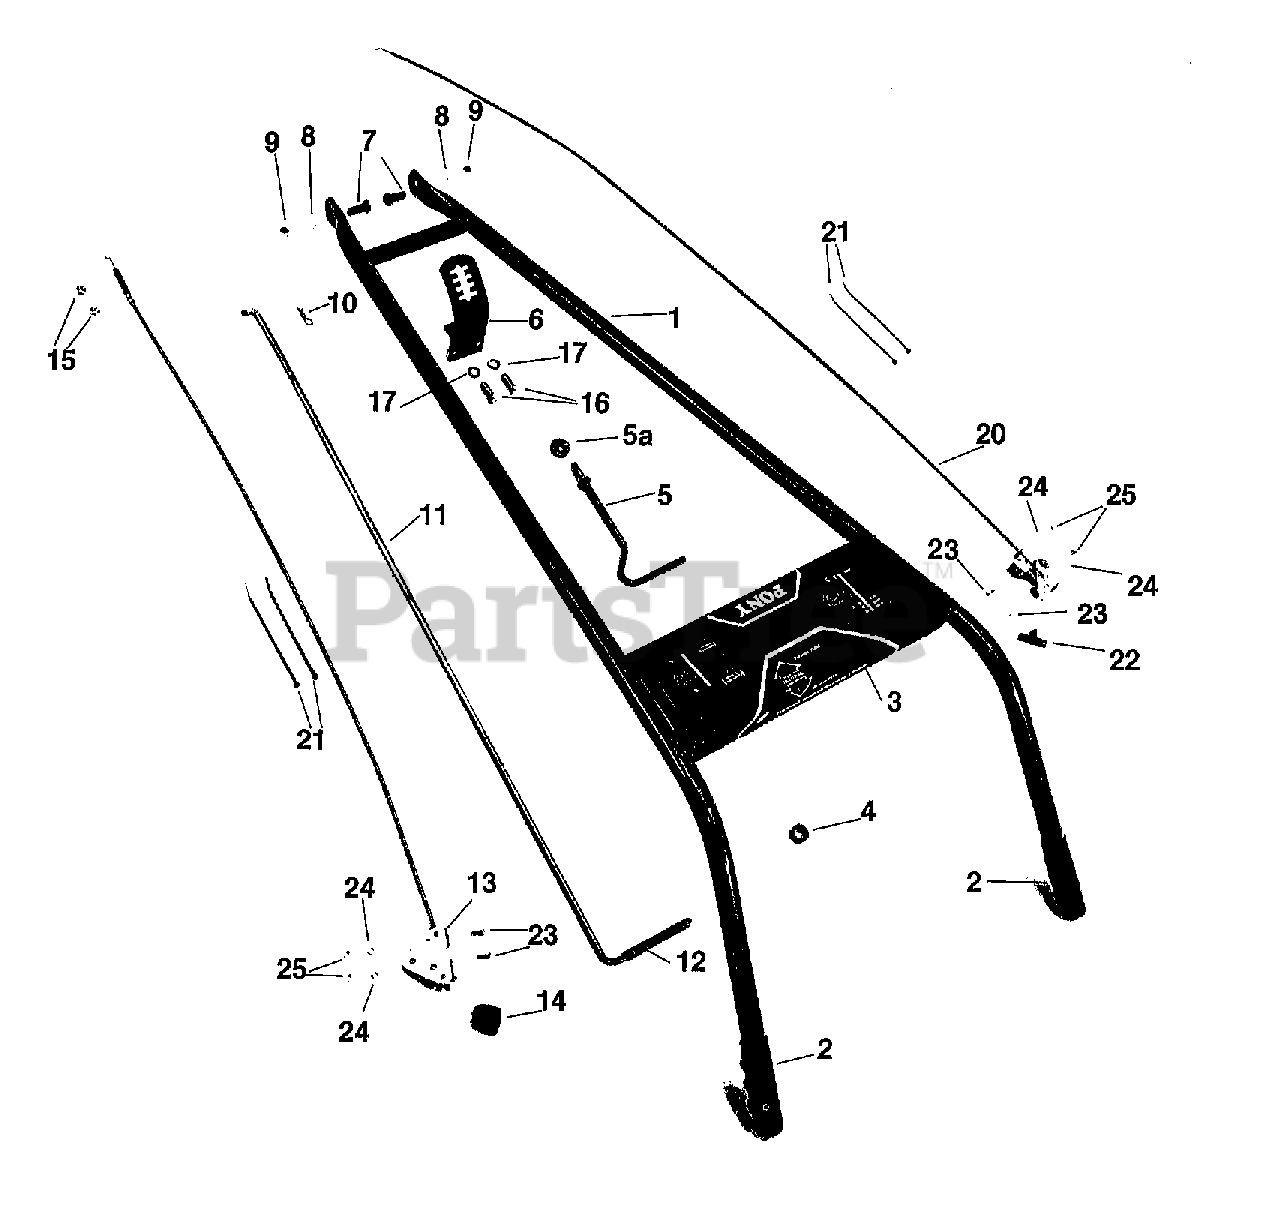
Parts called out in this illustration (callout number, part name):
1	HANDLEBARS-
2	GRIP-handlebars
3	DECAL- for operator control panel
4	GROMMET- plastic (part of operator control panel)
5	STUD-regulates handlebar height adjustment
5A	WASHER- keyed,
6	BRACKET- handlebar height adjustment
7	BOLT-hex head, 3/8"-16 x 1", Grade 5
8	WASHER -plain(flat), 3/8",S.A.E.(handlebar attachment)
9	LOCKNUT-hex, 3/8"-16 (handlebar attachment)
10	HITCH PIN-(connects Forward-Neutral-Reverse Lever to the shift mechanism)
11	FORWARD-NEUTRAL-REVERSE LEVER -complete
12	GRIP-Forward-Neutral-Reverse Lever
13	WHEEL DRIVE CONTROL & CABLE ASSY -
14	KNOB -Wheel Drive Control Lever
15	NUT-hex, 5/16"-24, wheel drive cable adjustment
16	BOLT-hex head, 3/8"-16 x 3/4"
17	LOCKWASHER-3/8"
20	THROTTLE CONTROL & CABLE-complete,
21	TIES-plastic (to secure cables to handlebars)
22	KNOB- throttle control lever
23	SCREW-round head, No. 10-32 x 1/2"
24	LOCKWASHER-No.10
25	NUT-hex, No. 10-32
